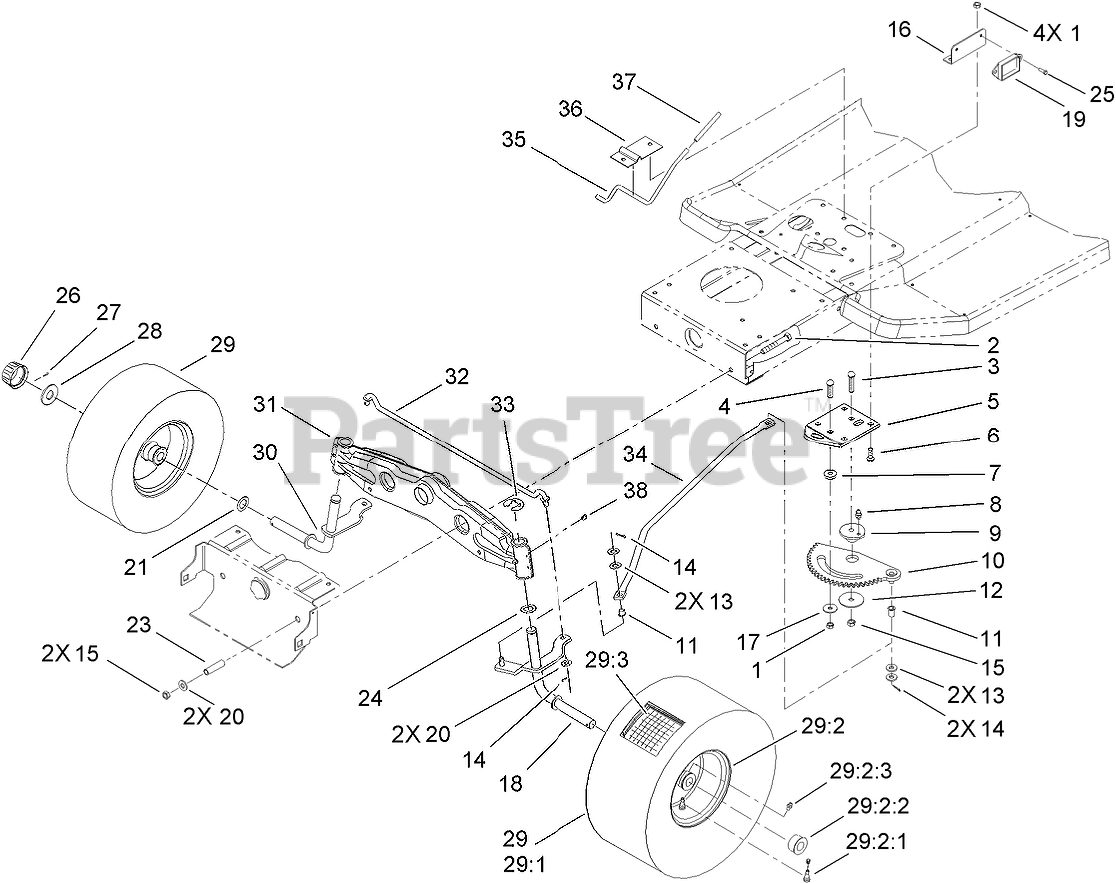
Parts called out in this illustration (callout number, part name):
1	NUT-LOCK, NI
2	SCREW-HH
3	SCREW-CARR
4	SCREW-CARR
5	BRACKET-RACK, STEERING
6	BOLT-CARR
7	SPACER-RACK, STEERING
8	FITTING-GREASE
9	BUSHING-ECCENTRIC
10	RACK-STEERING
11	BUSHING-FLANGED, NYLON
12	WASHER-BEARING
13	WASHER-FLAT
14	PIN-COTTER
15	NUT-LOCK, NI
16	BRACKET-MODULE
17	WASHER-PIVOT
18	LH SPINDLE ASM
19	MODULE-CLUTCH
20	WASHER-FLAT
21	WASHER-THRUST
23	SPACER
24	WASHER-THRUST
25	SCREW-HWH
26	CAP-HUB
27	PIN-COTTER
28	WASHER-PLAIN
29	WHEEL AND TIRE ASM
29:2:1	STEM-VALVE
29:2:2	BEARING-WHEEL
29:2:3	FITTING-GREASE
29:3	TUBE-INNER
30	RH SPINDLE ASM
31	AXLE-FRONT
32	TIE ROD-STEERING
33	E-RING
34	LINK-DRAG
35	ROD-BRAKE, PARKING
36	BRACKET-PARKING BRAKE
37	GRIP-BRAKE, PARKING
38	FITTING-GREASE
